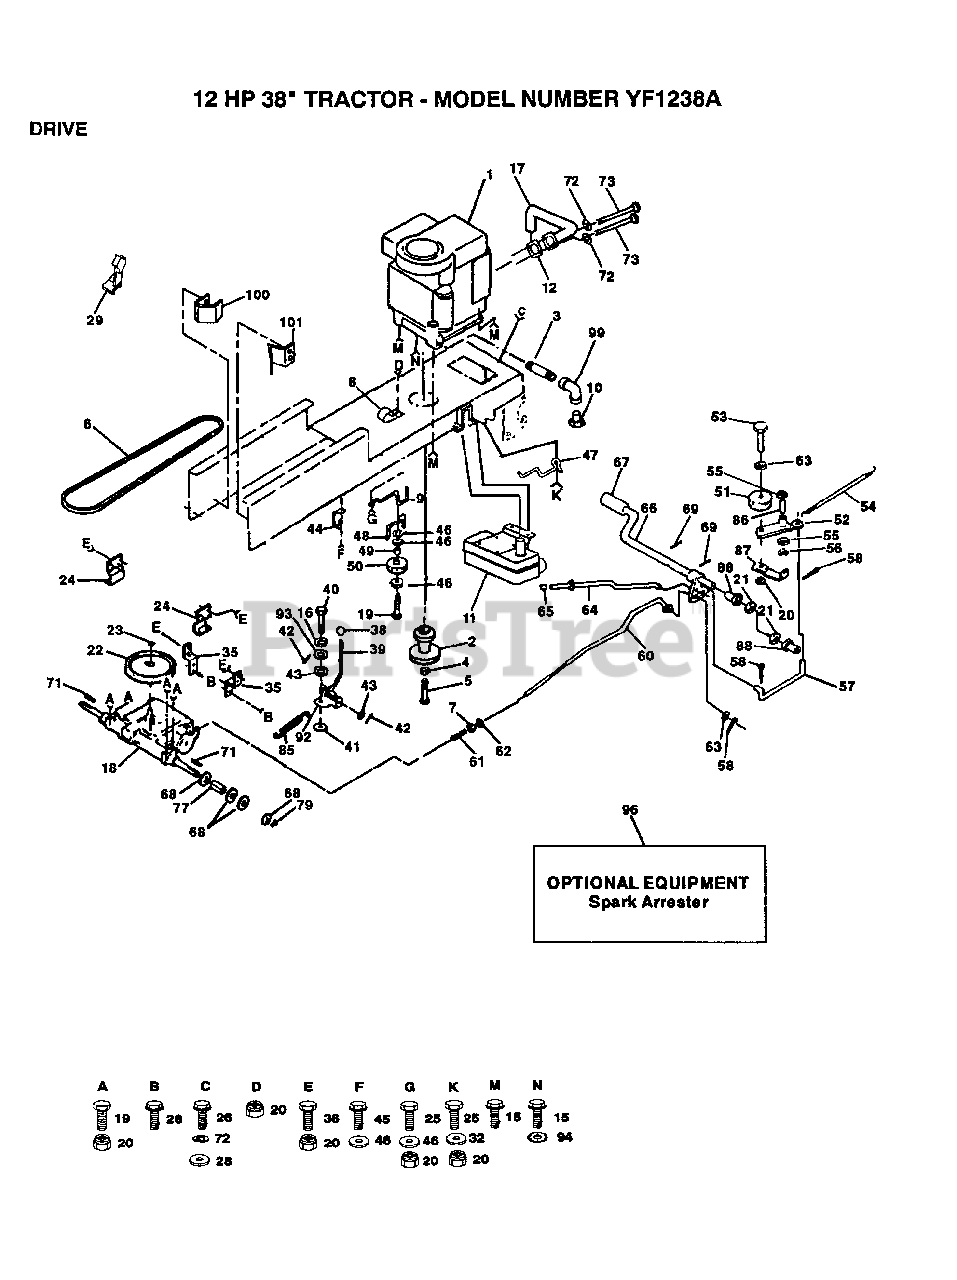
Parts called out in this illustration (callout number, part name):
3	PIPE NIPPLE
4	LOCKWASHER
5	BOLT
6	BELT-V.90.0.GD.DR
7	NUT
8	CLIP T
9	KEEPER.BELT.ENG.L
11	MUFFLER EUROPE
15	SCREW
16	LOCKWASHER
17	PIPE EXHAUST
19	BOLT
21	WASHER LT
22	PULLEY TRANS
24	BRACKET LT
25	BOLT
26	SCREW
28	WASHER
32	WASHER
35	STRAP TORQUE
38	KNOB T (1/2-HOLE)
39	ROD SHIFTER
41	WASH-SHFT PLT LT
42	PIN COTTER 1/8
43	WASHER
45	SCREW
46	WASHER
47	KEEPER BELT ENG
48	BELT KEEPER LT
49	SPACER T
50	PULLEY.IDLER.FLAT
52	ARM IDLER
54	"SPRING, RETURN LT"
55	WASHER LT
56	KLIP RING
57	"LINK, CLUTCH T"
58	COTTER PIN
61	SPRING ROD LT
62	NUT
63	WASHER
64	PARKING BRAKE ROD
65	PLUNGER CAP T
67	PEDAL COVER T
68	WASHER
71	SQUARE KEY
72	LOCKWASHER
73	SCREW LT
77	SPACER LT
79	E-RING LT
86	"LY, BEARING"
87	RETAIN BELT
88	NYLON BEARING
92	PLATE SHIFT LT
93	WASHER LT
94	LOCKWASHER
99	ELBOW
100	"KEEPER,BELT LH T"
101	"KEEPER,BELT RH T"
